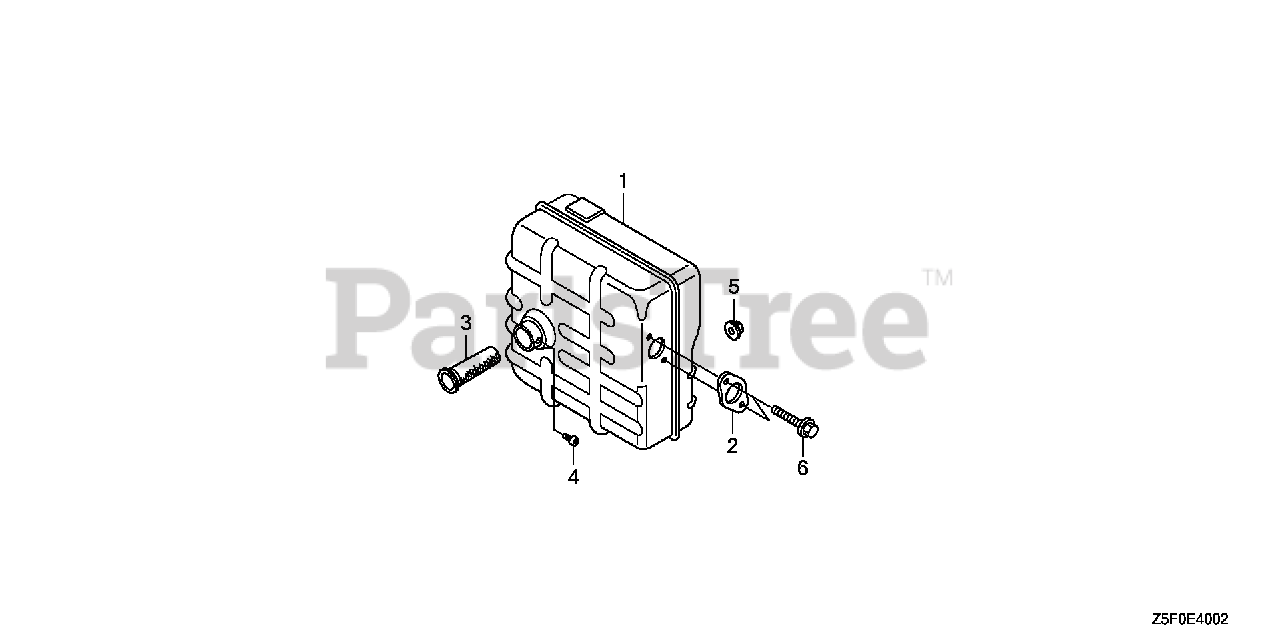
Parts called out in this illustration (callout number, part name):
1	MUFFLER (TSURUMI)
2	GASKET, EX. PIPE
3	ARRESTER, SPARK
4	SCREW, TAPPING (4X8)
5	NUT, FLANGE (8MM)
6	BOLT, FLANGE (8X20)
